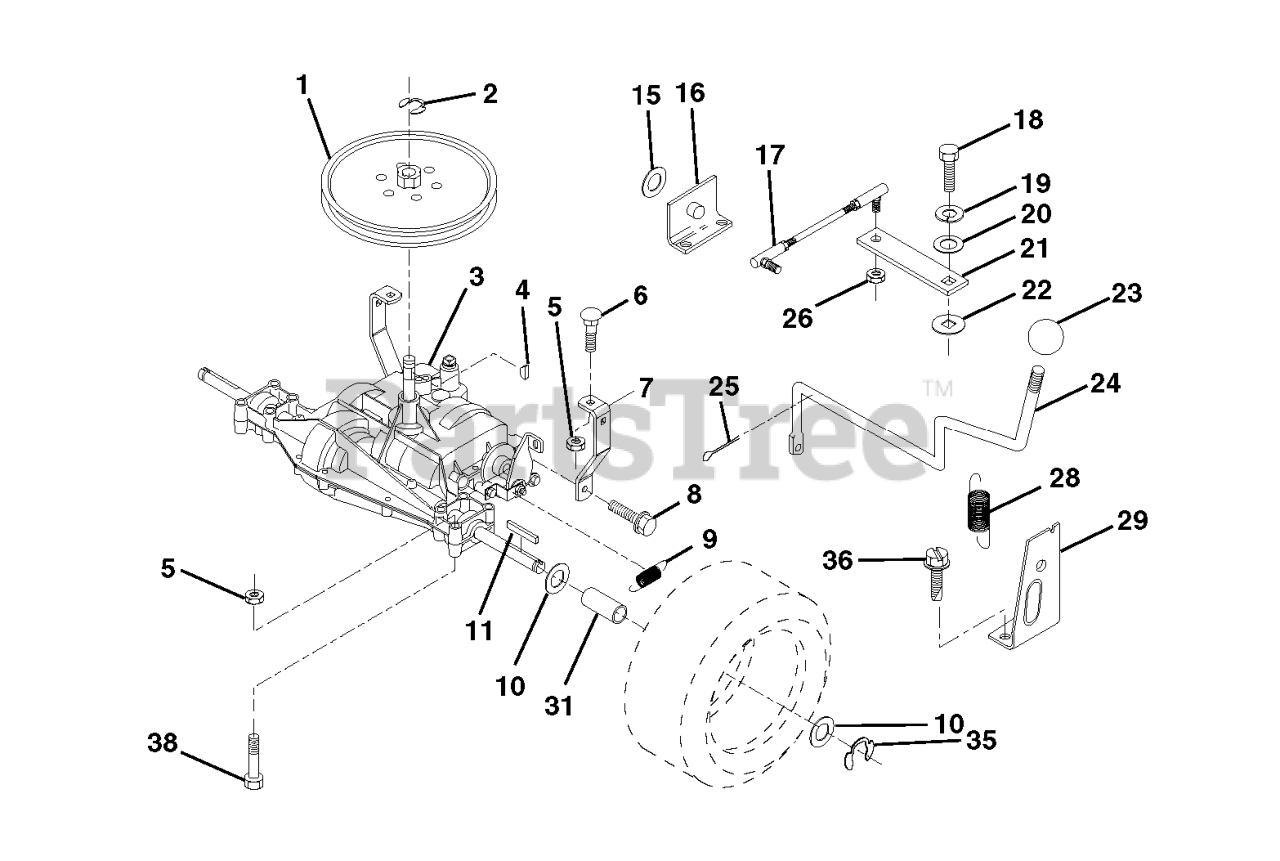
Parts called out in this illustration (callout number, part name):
2	RETAINING RING LT
4	KEY STD (1373) DANA
5	LOCKNUT
6	RP BOLT 5/16-18 X3/4 ZN/YEL GR
7	STRAP,TORQUE
8	SCREW.THDROL.5/16-18X3/4.TTY
9	SPRING,BRAKE RETURN
11	SQUARE KEY
15	WASHER
16	SUPT, HDLE SHT LH
18	BOLT 1/4-28X3/4
19	LOCKWASHER
22	WASH-SHFT PLT LT
23	KNOB T (1/2-HOLE)
24	ROD, SHIFT
25	PIN COTTER
26	LOCKNUT
28	SPRING.EXTENSION
29	SUPPORT HANDLE SHAFT RH
31	SPACER AXLE
36	SCREW
38	BOLT HEX 5/16-18 GR 5
